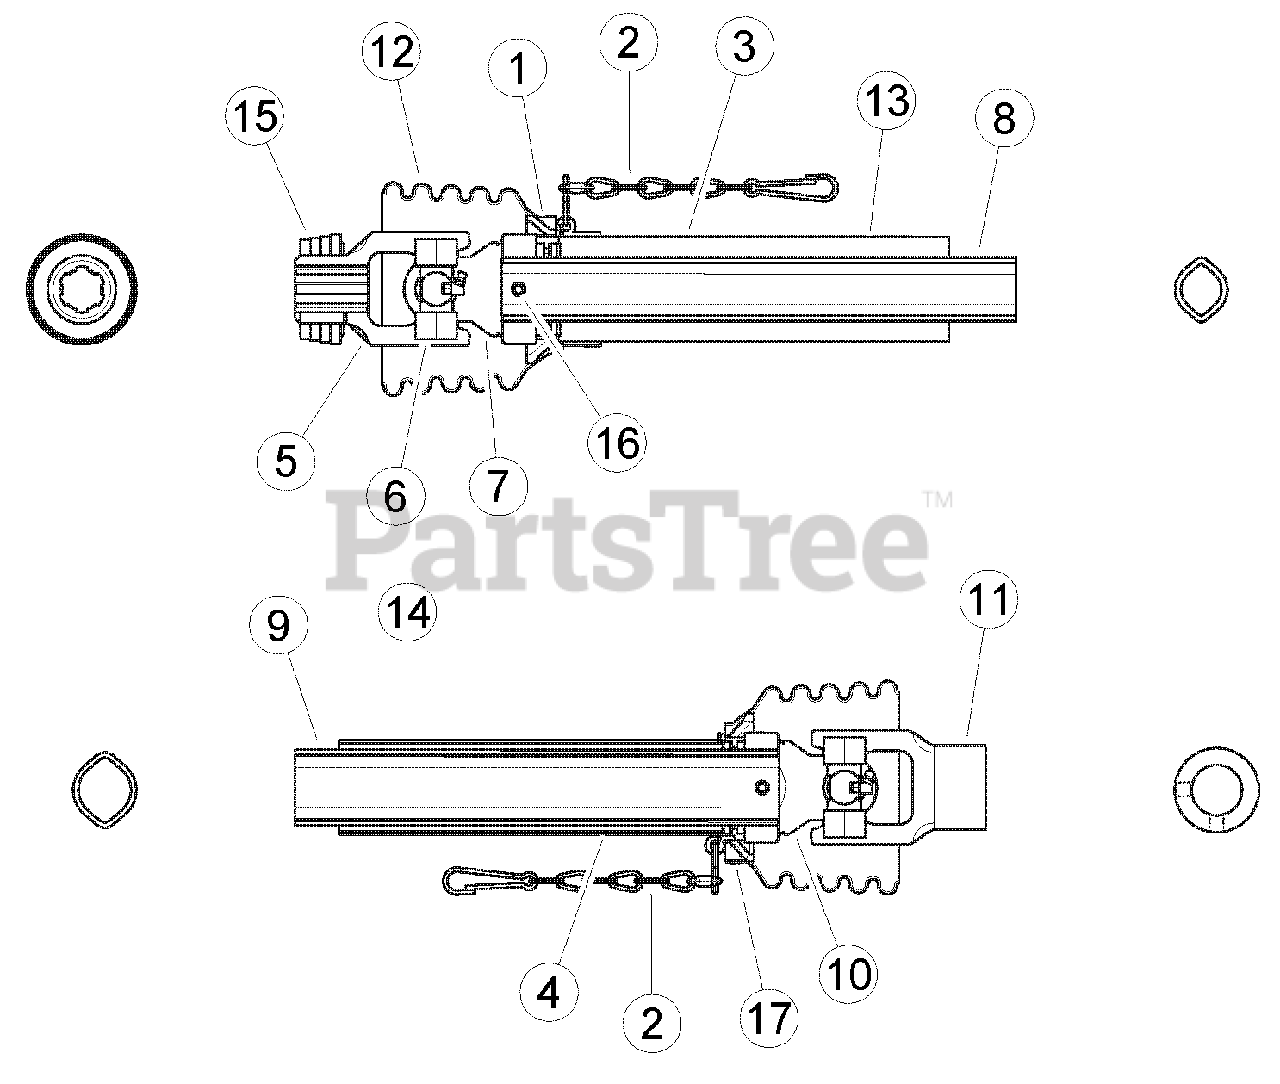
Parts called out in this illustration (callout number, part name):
1	BEARING, RING SC15
2	SAFETY CHAIN
3	DECAL, OUT
4	DECAL, IN
5	YOKE, 3/8 - 6 SPL. ASGE
6	CROSS & BEARING KIT
7	YOKE, INBOARD OV
8	INNER PROFILE OV
9	OUTER PROFILE I
10	YOKE, INBOARD I
12	SHIELD, CONE 4 RIB
13	SHIELD, OUTER TUBE OVL.
14	SHIELD, INNER TUBE RND
15	KIT, RETAINING RING / TRACTOR SIDE
16	PIN, SPRING 10 X 65
